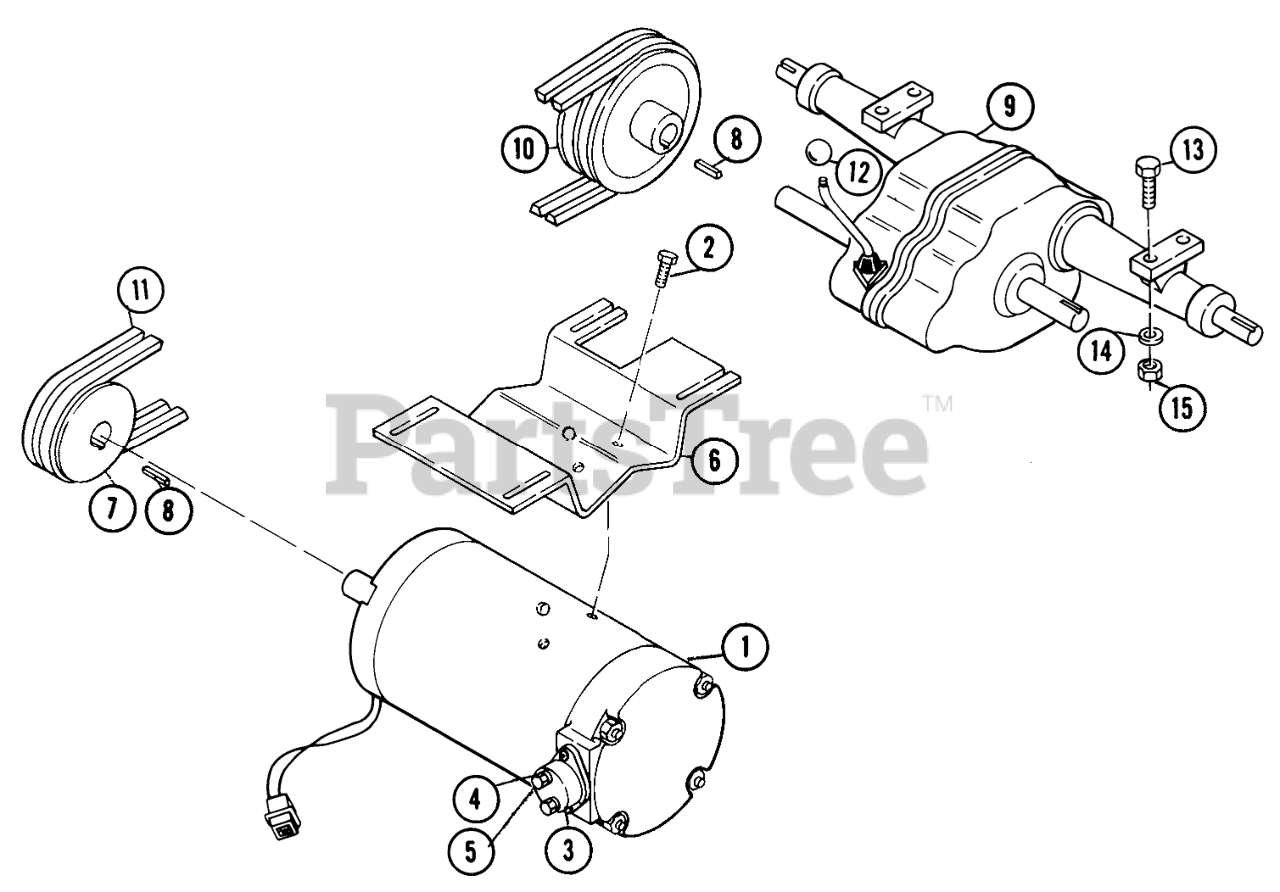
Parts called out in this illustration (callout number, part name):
9-01	Motor
9-02	Bolt, Hex 5/16-18 x 5/8
9-03	Circuit Breaker (CB-1)
9-04	Mach. Screw, Pan Hd. #10-32 x 3/4
9-05	Lockwasher #10
9-06	Mounting Plate, Motor
9-07	Pulley, Drive Motor
9-08	Key, 3/16 x 3/4
9-09	Transaxle Assembly
9-10	Pulley, Transmission
9-11	Drive Belt (Matched Pair)
9-12	Knob, Gear Shift
9-13	Cap Screw, Hex 3/8-16 x 1 3/4
9-14	Spring Lockwasher
9-15	Nut, Hex 3/8-16
